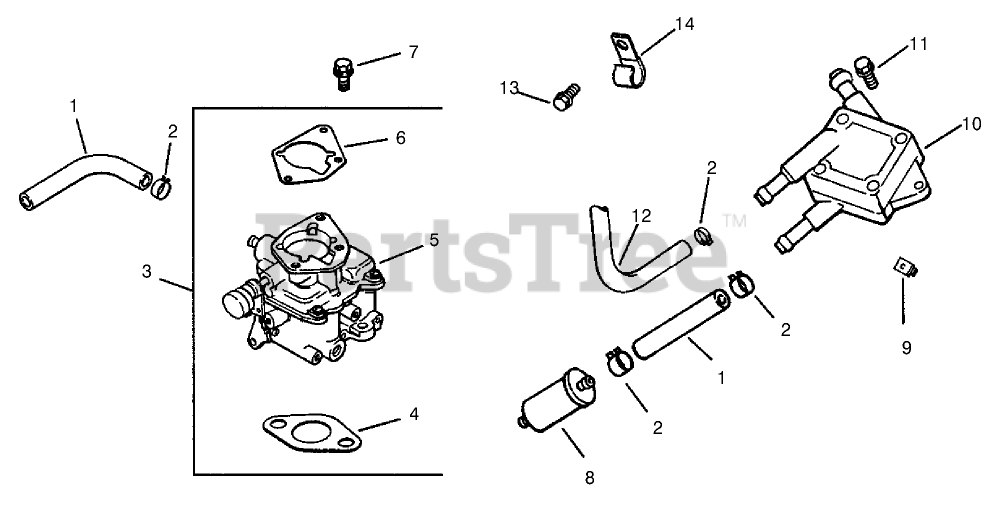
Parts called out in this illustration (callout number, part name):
1	Line-Fuel 9"
2	Clamp
3	Kit, carburetor w/gasket (Includes 4-6)
4	GASKET-BASE, AIR CLEANER
5	Carburetor assembly (For information only not available seperately)(Includes 24 757 01-S, 24 757 02-S, 24 757 03-S, & 24 757 07-S,
6	Gasket-Carburetor
7	SCREW-FLANGE (M6X1.0X30)
8	Filter-Fuel
9	Nut-Plastic
10	PUMP-FUEL
11	SCREW-TAP (M6X1.7X18)
12	Line-Fuel, Flexible (15.5)
13	Screw-HF (M6x1.0x12)
14	Clip, cable
